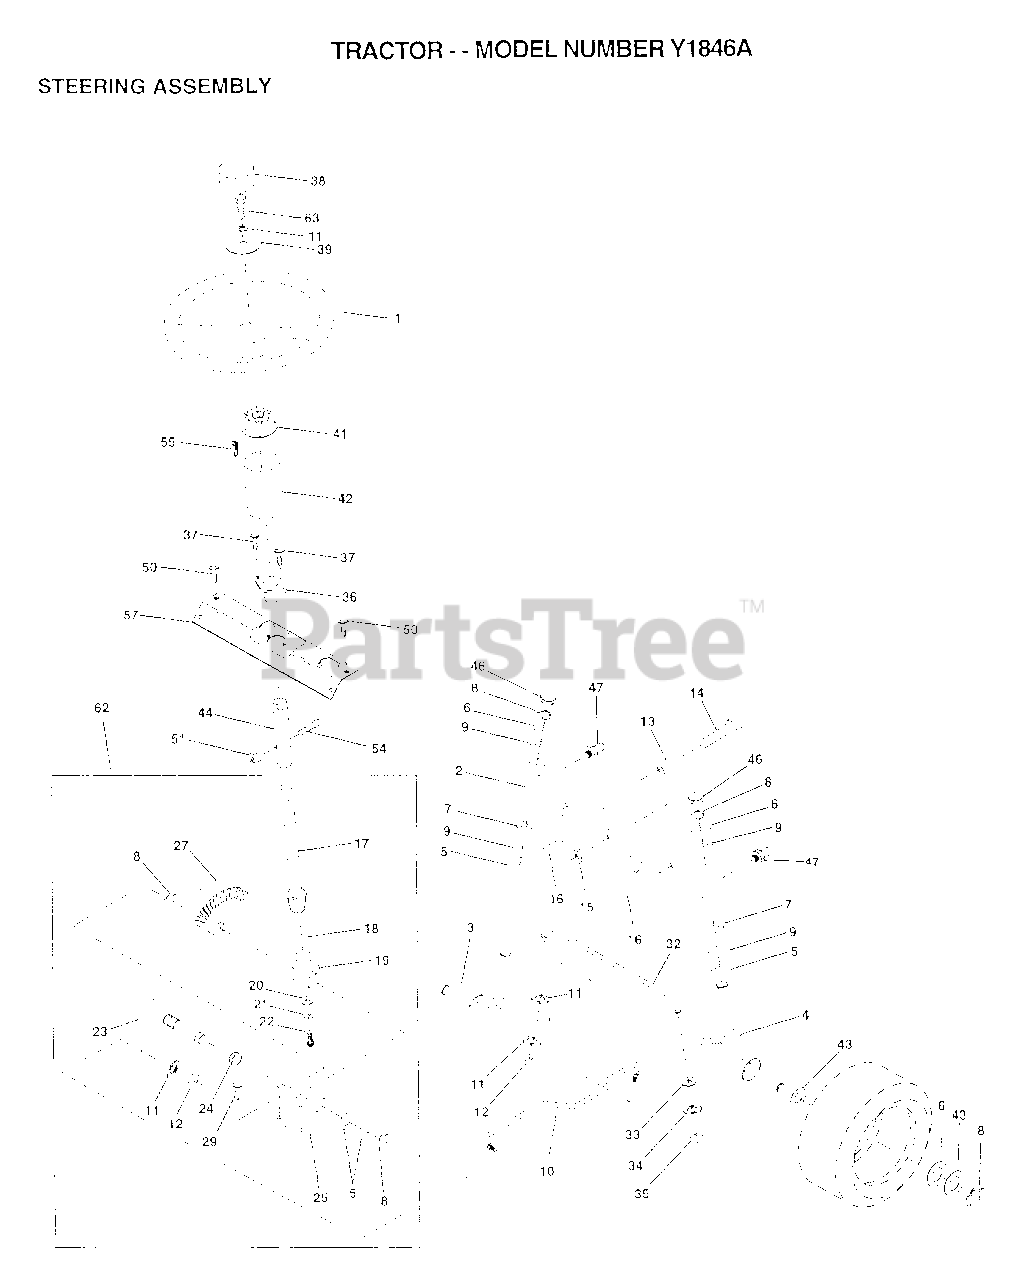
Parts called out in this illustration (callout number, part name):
2	AXLE ASM FRONT
3	SPINDLE LH
4	SPINDLE RH
5	WASHER .T
7	WASHER
8	RING
9	COL. SRTG. BEAR.
11	LOCKWASHER
13	BEARING
14	BOLT HEX 5/8-11
15	"NUT-LOC,FLANGE LT"
16	AXLE PIN
17	SHAFT ASM STEERIN
18	THRUST WASHER
19	SUPPORT.SHAFT
21	LOCKWASHER
22	SCREW.SCKTHD.CAP
24	NYLINER T
25	"BRKT,STEERING"
27	GEAR SECTOR
29	SCREW
32	TIE ROD
33	WASHER M
34	LOCKWASHER
35	NUT.LOCK.5/16-24
37	"SCREW-TT,10-32 FL"
38	"INSERT,STR WHEEL"
39	WASHER T
41	ADAPTER LT
42	BOOT SHAFT STEER
43	WASHER
44	SHAFT EXT STEERIN
46	CAP
47	ZERK M
50	SCREW HEX CRT
51	NUT
54	BOLT
55	CLIP TINNERMAN
57	SUPPORT SHAFT STR
63	BOLT
